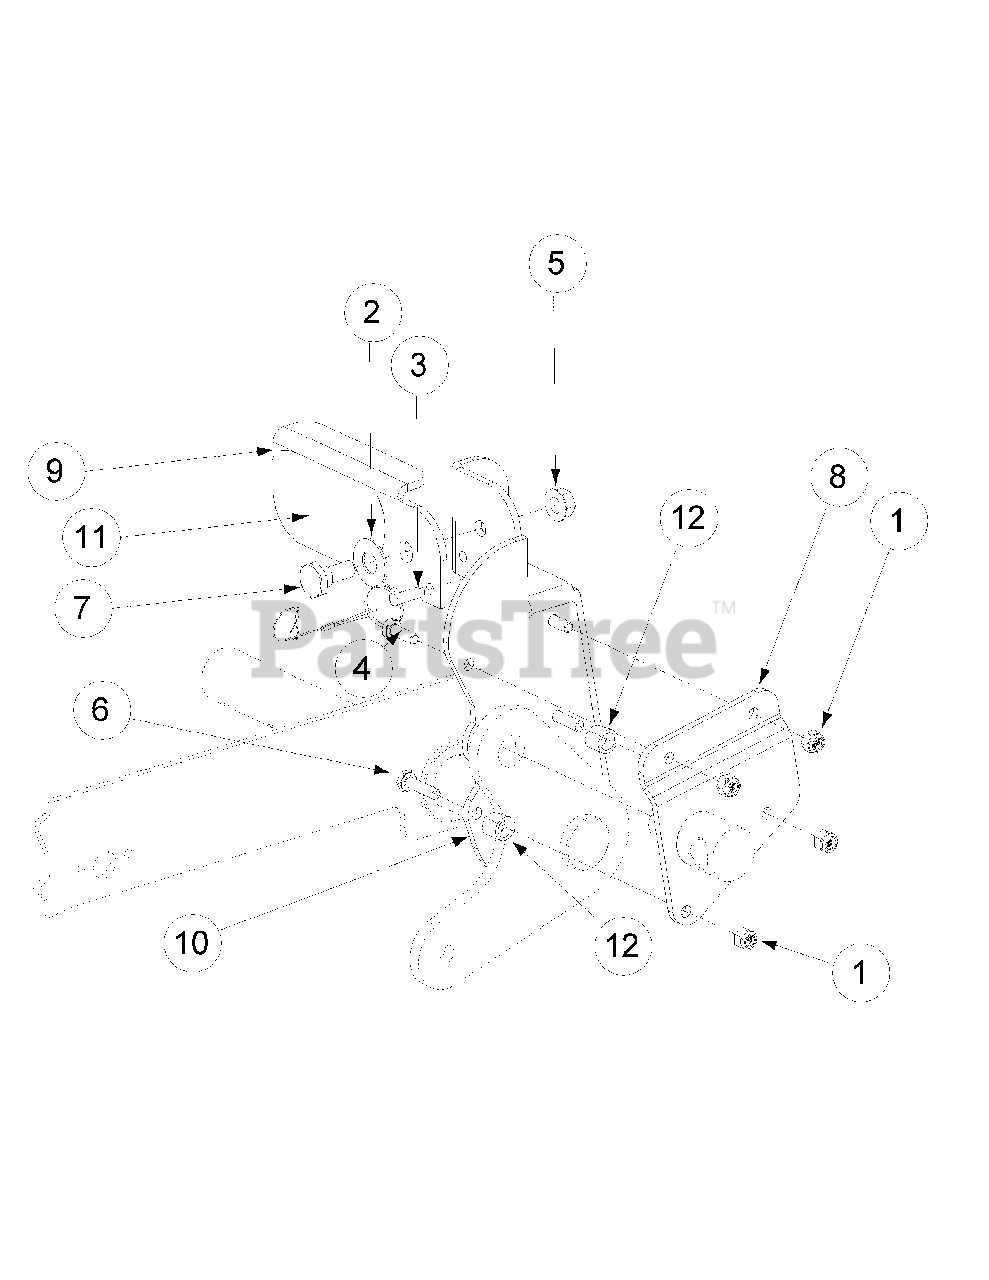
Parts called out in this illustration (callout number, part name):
1	Lock Nut, Nylon Insert, 1/4-20
2	Washer, 1/2 x 1 Shim
3	Detent Pin w/12" Lanyard
4	Hex Cap Screw, 1/4-20, .75
5	Hex Nut, Flange Lock 3/8-16
6	Hex Cap Screw, 1/4-20, 1.00
7	Shoulder Screw, .50 x .27 Lg., 3/8-16
8	Foot Lift Backup Pedal
9	Deck Foot Pedal Lift
10	Deck Foot Pedal Lift
11	Deck Foot Lift Pad
12	Turnbuckle Sleeve
